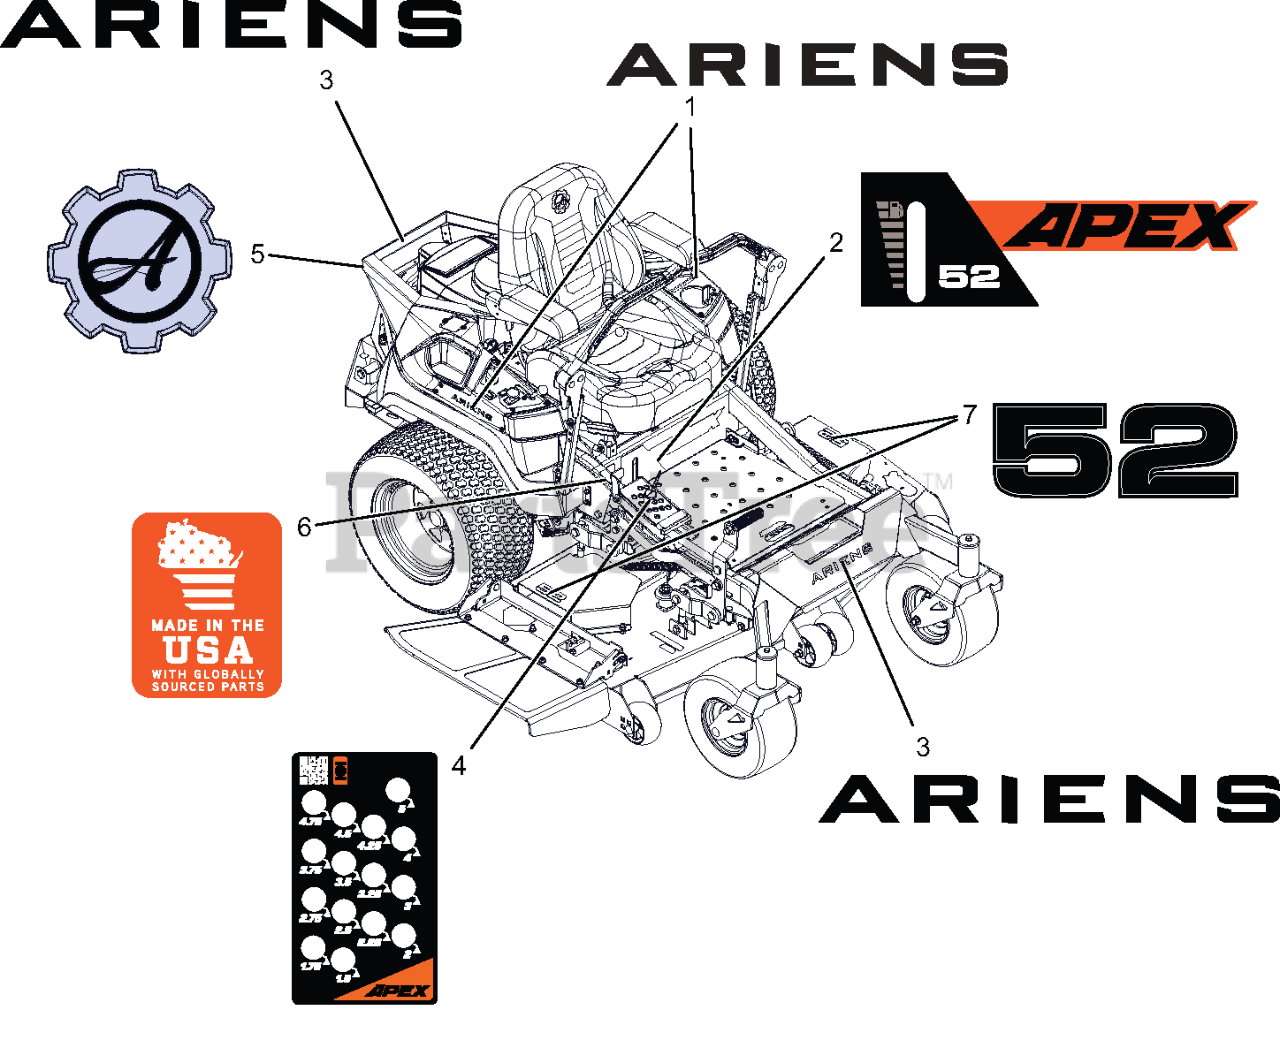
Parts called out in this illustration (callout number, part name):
1	DECAL- ARIENS 6.000" BLACK
2	DECAL- APEX 52 KICKPLATE
3	DECAL- ARIENS 9.625" BLACK
4	DECAL- APEX HOC
5	DECAL- ARIENS GEAR BADGE
6	DECAL- MADE IN USA
7	DECAL- DECK 52
